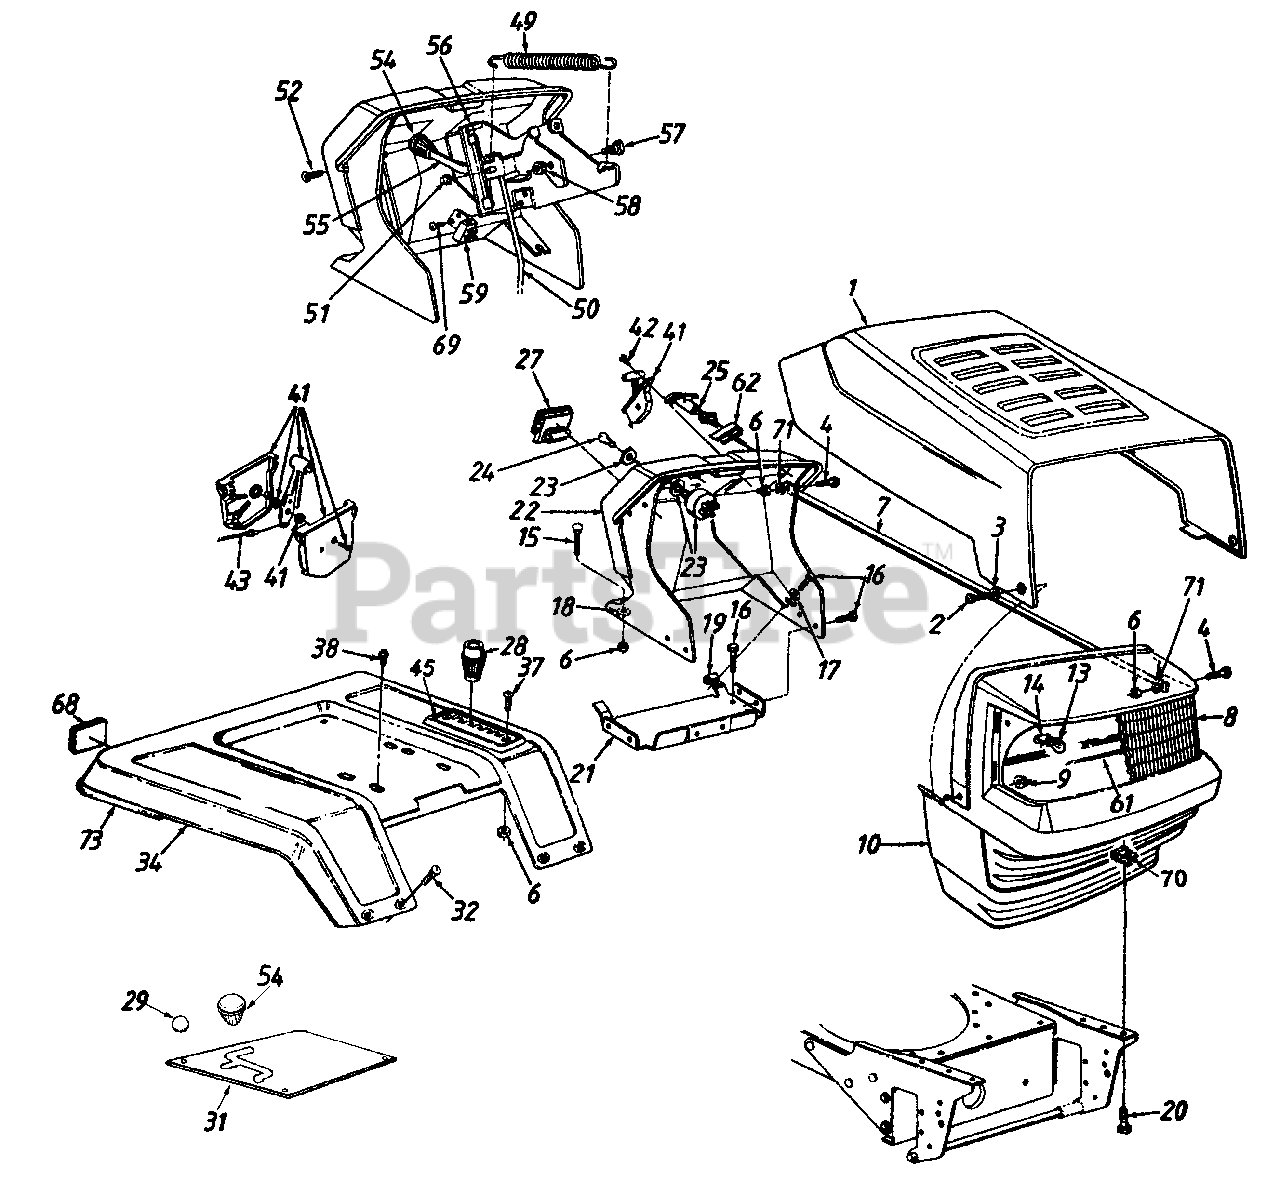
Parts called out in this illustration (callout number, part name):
3	Spr. Wash. .265" I.D. x .562" O.D.
4	Hex Bolt 1/4-20 x .62" Lg.
6	Hex Sems Nut 1/4-20 Thd.
9	Flange L-Nut 1/4-20Thd.
10	Grille
13	Lamp
14	Socket
15	Carriage Bolt 1/4-20 x 1.0" Lg.
16	Hex AB-Tap Scr. 1/4 x .62" Lg.
17	Fl-Wash. .281" I.D. x .73" O.D.
18	Bolt Retainer 1/4" I.D.
19	Speed Nut 1/4-20 Thd.
20	Hex Bolt 5/16-18 x .75" Lg.
23	Ignition Switch
24	Ignition Key
25	Choke Control
27	Ammeter
28	Shift Knob
38	Hex Wash. Hd. AB-Tap Scr. 5/16 x .75" Lg.
41	Throttle Box Ass'y.
42	Truss Mach. AB-Tap Scr. #10 x .5" Lg.
43	Throttle Control Wire 35" Lg.
45	6-Speed Selector Plate
49	Ext. Spring 5.06" Lg.
50	Deck Control Rod
51	Speed Nut 1/4" Rod
52	Torx Mach. Scr. 1/4 x .62" Lg.
54	PTO Knob
55	PTO Lever
58	Hex L-Nut 5/16-18 Thd.
59	Safety Switch
61	Grille Reflector Label
62	Retainer Clip
68	Reflector
69	Hex Wash. Hd. B-Tap Scr. 10 x .38" Lg.
70	U-Nut 5/16-18 Thd.
71	Fl-Wash. .28" I.D. x .75" O.D.
73	Trim Strip 81" Lg.
17426A-0638	FENDER-RR - MTD/TROY-BILT RED (0638)
17426A-0648	FENDER-RR - TECH GRAY (0648)
